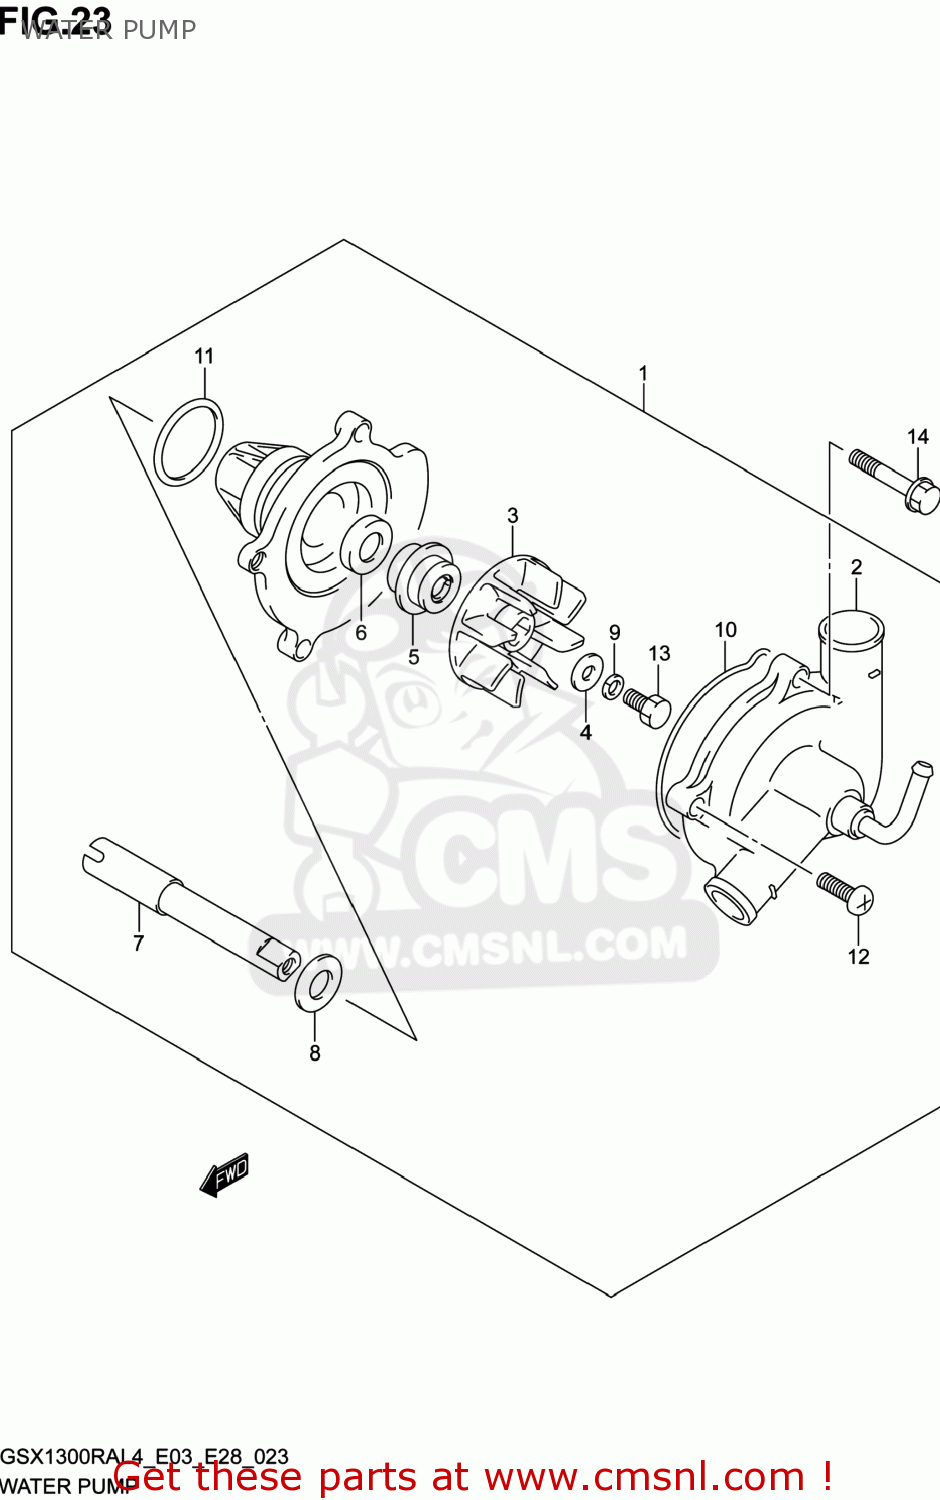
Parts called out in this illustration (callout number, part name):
1	PUMP ASSY,WATER
2	CASE
3	IMPELLER
4	GASKET(6X15X2.2) (NAS)
5	SEAL,MECHANICAL
6	SEAL,OIL
7	SHAFT
8	WASHER
9	WASHER
10	O RING
11	O RING,WATER PUMP HOLDER
12	SCREW
13	BOLT(6X13)
14	BOLT
